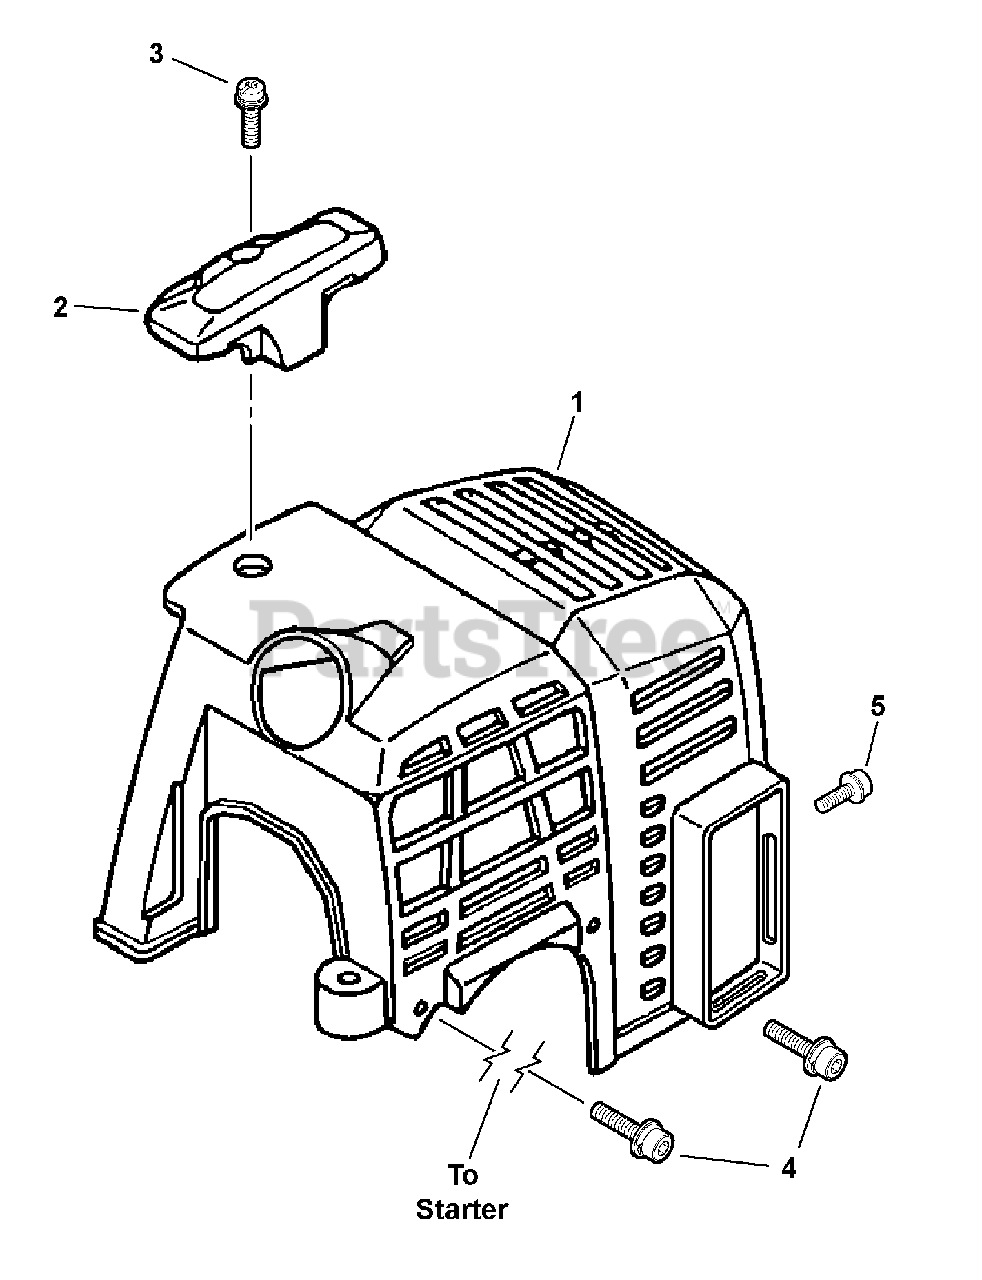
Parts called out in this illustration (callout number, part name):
1	COVER, ENGINE
2	GUARD, TOP
3	SCREW 5×16
4	BOLT 4×16
5	BOLT 4×8
